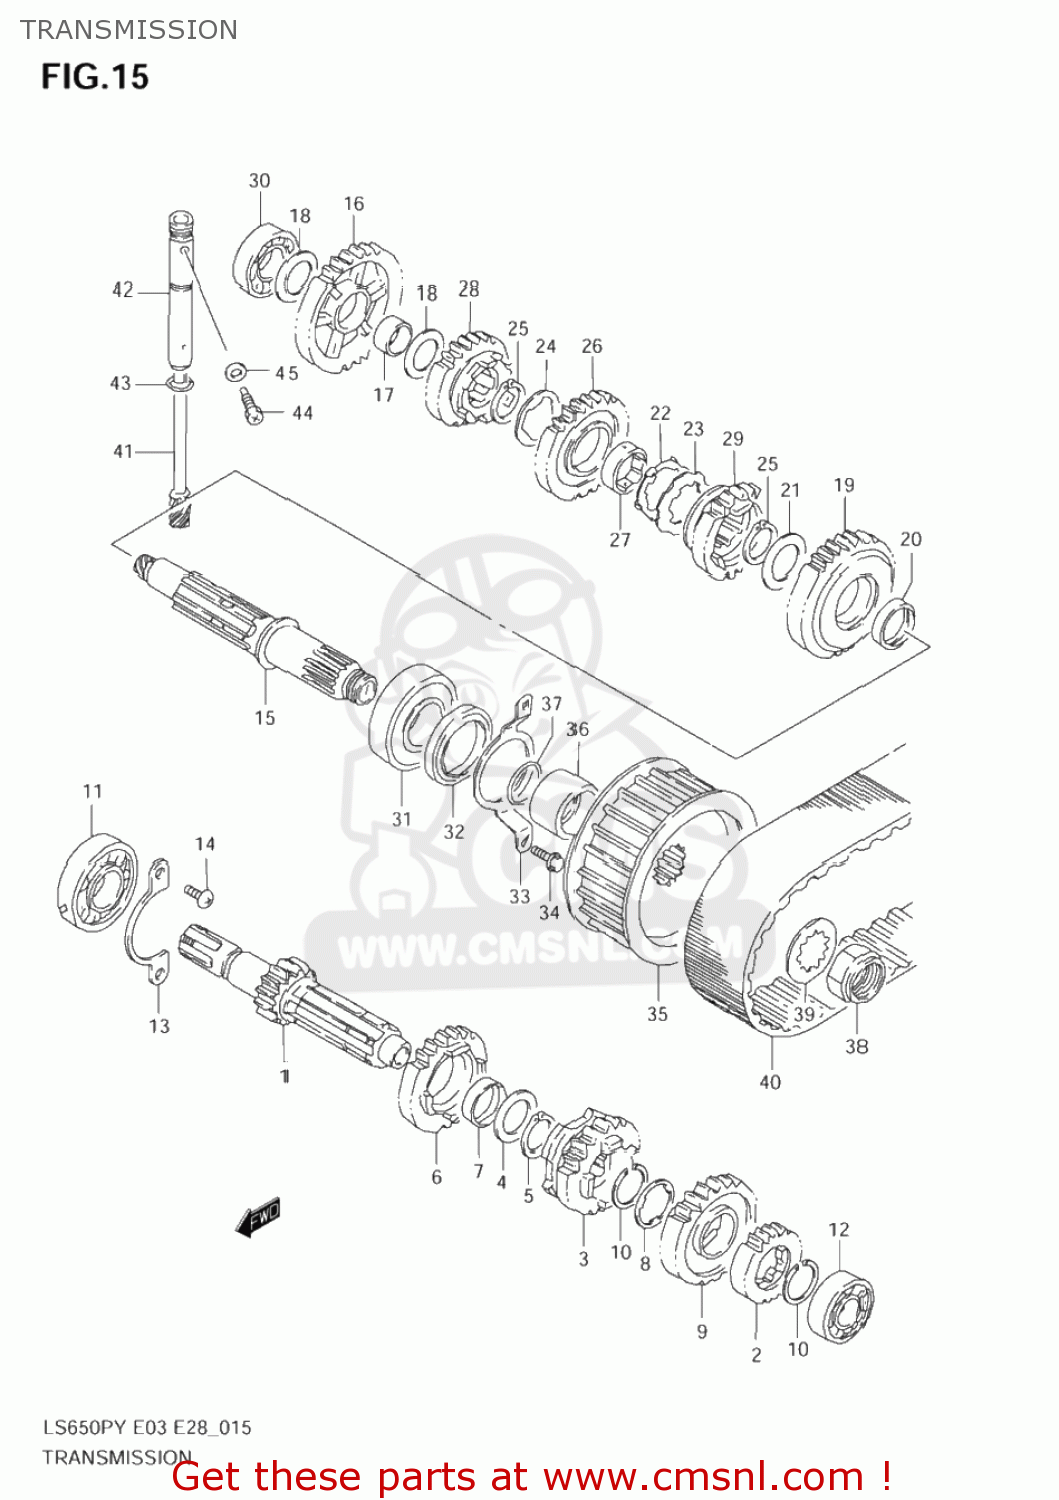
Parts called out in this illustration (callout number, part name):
1	SHAFT,COUNTER
2	GEAR,2ND DRIVE
3	GEAR,THIRD DRIVE
4	WASHER
5	RING,SNAP
6	GEAR,FOURTH DRIVE
7	BUSH
8	WASHER,LOCK
9	GEAR,5TH DRIVE
10	CIRCLIP
11	BEARING(22X56X16)
12	BEARING(17X40X12)
13	RETAINER,CNTR SHAFT BEARING
14	SCREW
15	SHAFT,DRIVE
16	GEAR,1ST DRIVEN(NT:35)
17	BUSH(20X24X13)
18	WASHER
19	GEAR,2ND DRIVEN
20	BUSH(25X29X8)
21	WASHER
22	WASHER
23	WASHER,LOCK
24	WASHER,LOCK
25	RING,SNAP
26	GEAR,3RD DRIVEN
27	BUSHING
28	GEAR,FOURTH DRIVEN
29	GEAR,5TH DRIVEN
30	BEARING(20X42X12)
31	BALL BEARING 25X62X17
32	SEAL,OIL(36X50X6)
33	RETAINER,DRIVE SHAFT OIL SEAL
34	BOLT
35	PULLEY,FR
36	SPACER,FR PULLEY
37	O RING(D:2.4,ID:23.7)
38	NUT
39	WASHER
40	BELT,DRIVE
41	GEAR,SPEEDOMETER DRIVEN
42	SLEEVE,TACHOMETER DRIVEN GEAR
43	O RING(D:1.3,ID:9.6)
44	BOLT
45	GASKET(6.2X11X1).2 (NAS)
